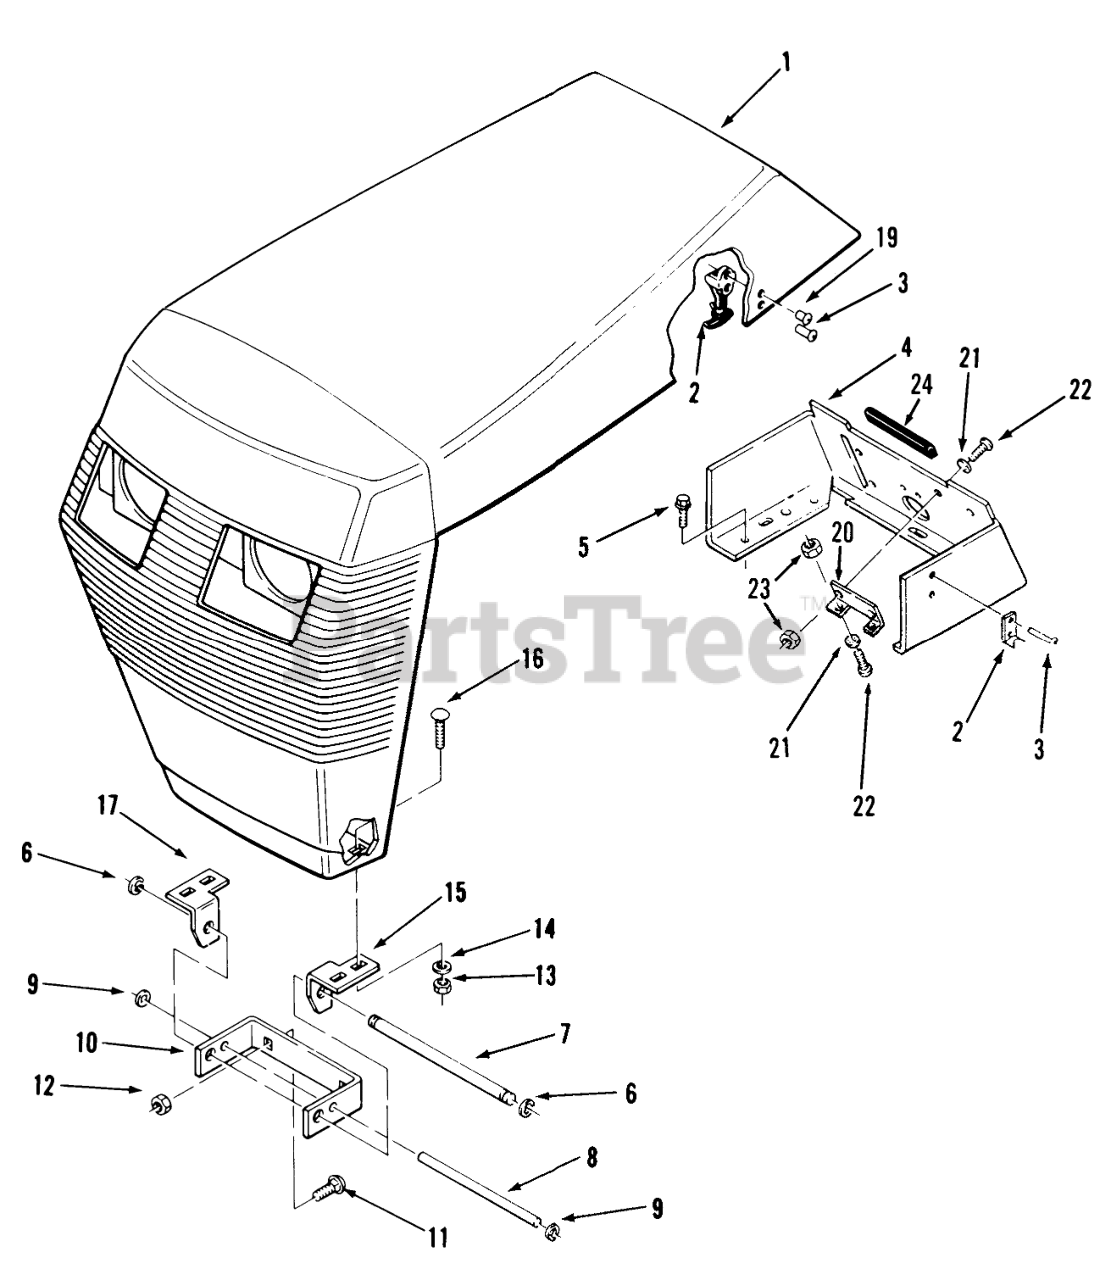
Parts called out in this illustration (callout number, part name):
1	Hood
2	ASSY-FLEX DRAW LATCH
3	RIVET -4
4	Console 252-H
4	Console
5	SCREW
6	RING-RETAINING
7	ROD-GRILL PIVOT
8	ROD-HOOD STOP
9	SPEED NUT
10	Bracket-Hood Pivot
11	Bolt-Carriage
12	Nut
13	Nut
15	BRKT-GRILL PIVOT R (NS)
16	Bolt-Carriage
16	Carriage Bolt 1/4-20 x 1
17	BRKT-GRILL PIVOT R
19	RIVET
20	BRACKET
21	Washer-Lock
22	SCREW-PAN
23	Nut
24	EDGING-CONSOLE
